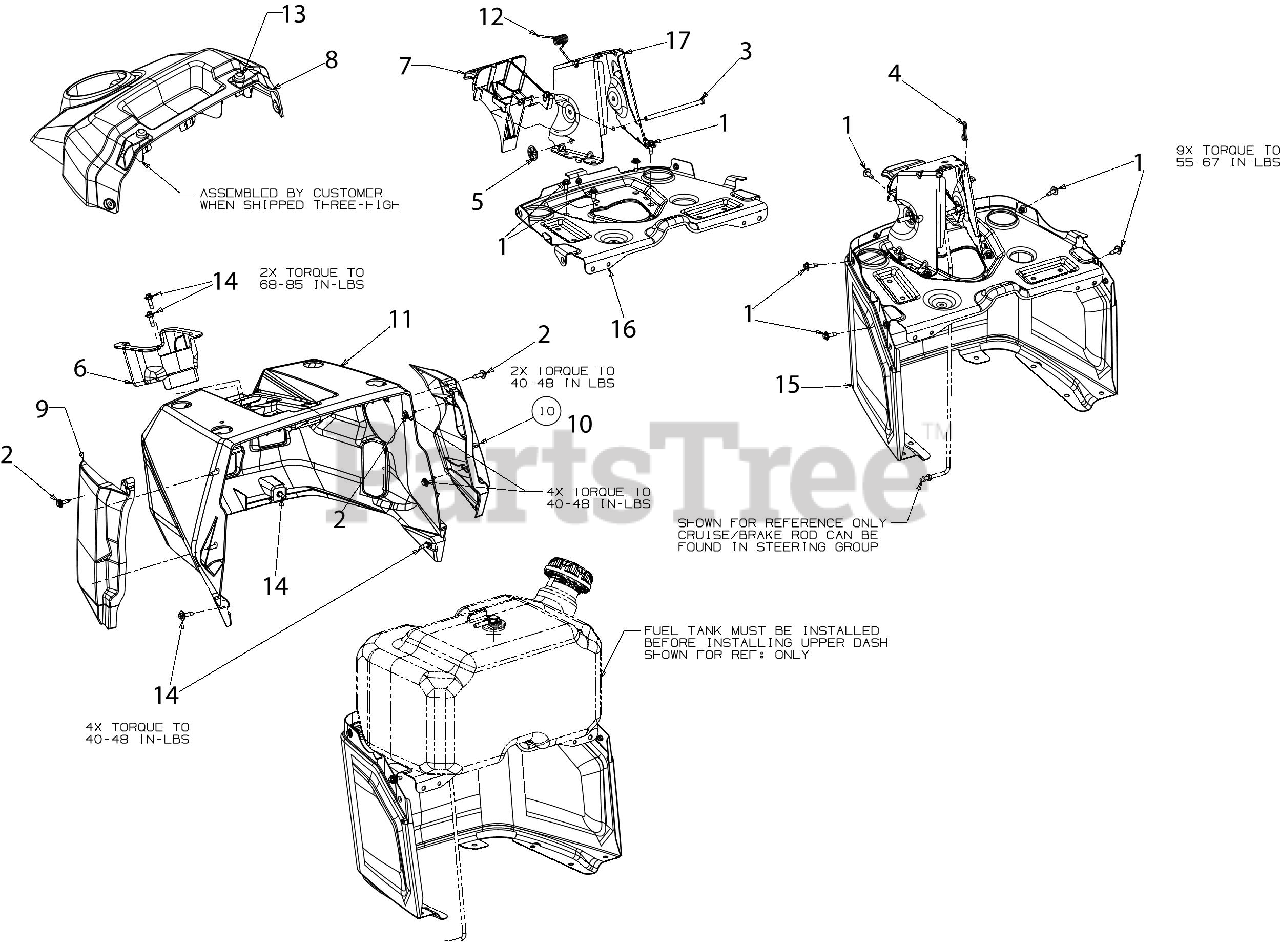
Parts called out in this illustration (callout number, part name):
1	SCREW M6-1 x .625
2	SCREW 1/4-10 x .750
3	HINGE PIN .25 x 4.50
4	BOW TIE COTTER PIN 1/4-5/16
5	PUSH ON NUT
6	STEERING SHAFT BEARING
7	CRUISE/BRAKE DASH LEVER
8	UPPER DASH CAP
9	DASH SIDE CAP (RH)
10	DASH SIDE CAP (LH)
11	UPPER DASH CAP (CRAFTSMAN)
12	TORSION SPRING .330 ID
13	BUMPER, .62 DIA x .3
14	SHOULDER SCREW M6-1 .368 X.115
15	LOWER DASH
16	DASH/FUEL TANK PLATE
17	STEERING MOUNT BRACKET
